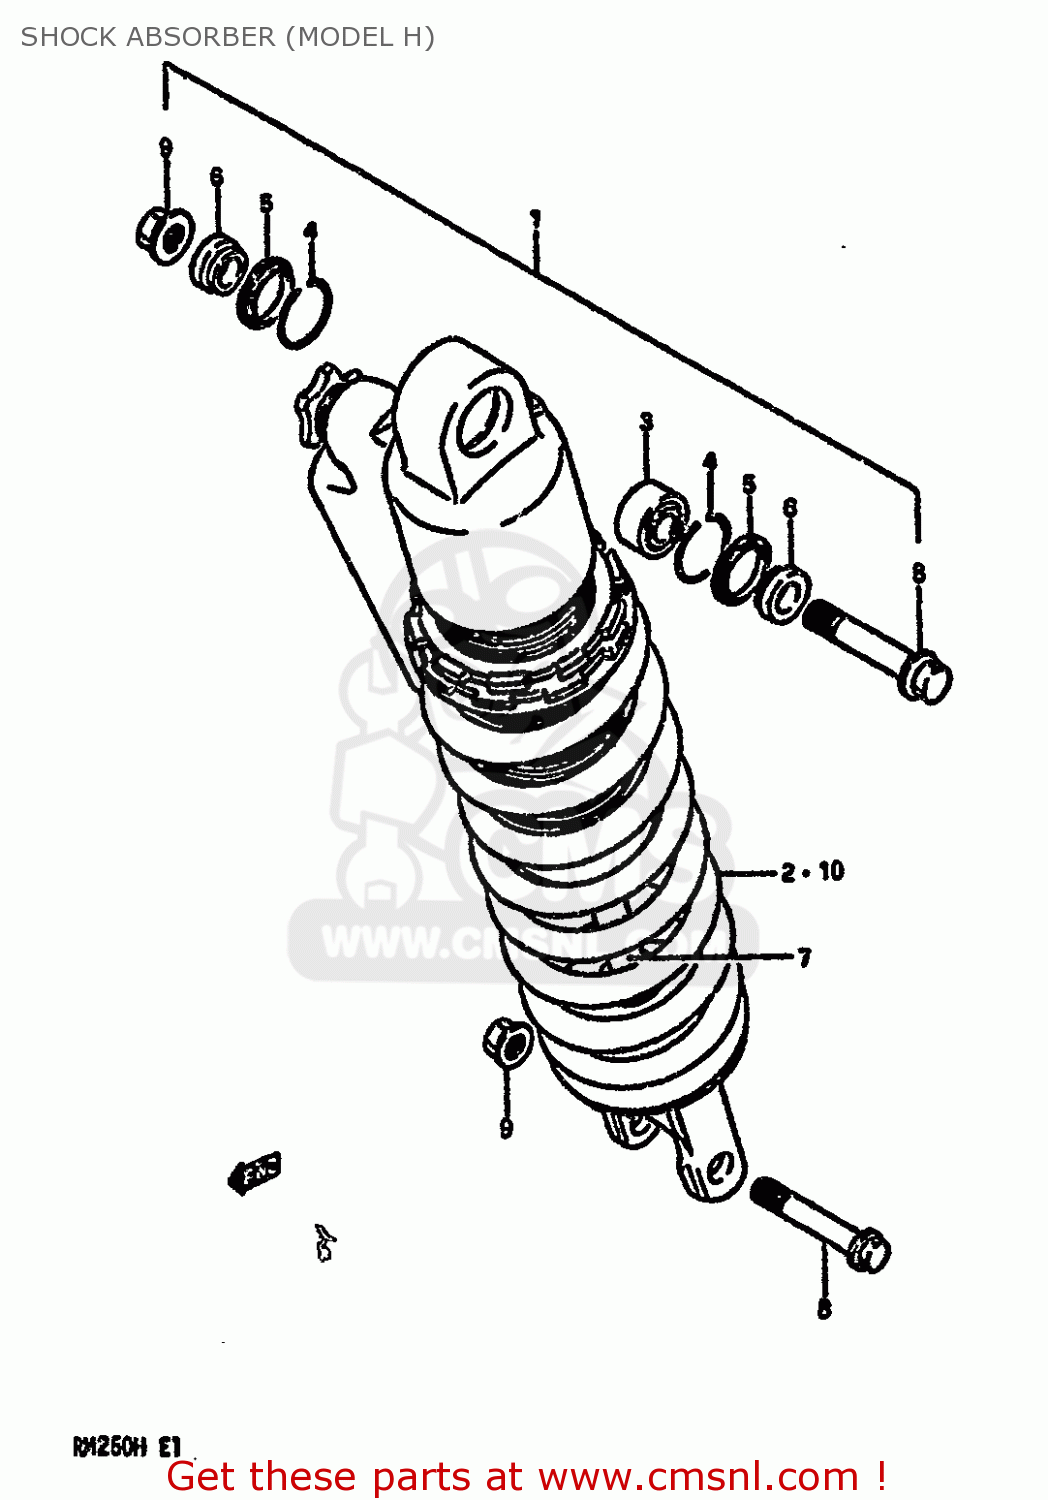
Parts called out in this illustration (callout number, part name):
1	ABSORBER ASSEMBLY,REAR SHOCK
2	SPRING
3	BEARING,RR CUSHION LEVER
4	RING
5	DUST SEAL
6	SPACER
7	ROD,PISTON
8	BOLT,REAR SHOCK ABSORBER
9	NUT
10	SPRING
